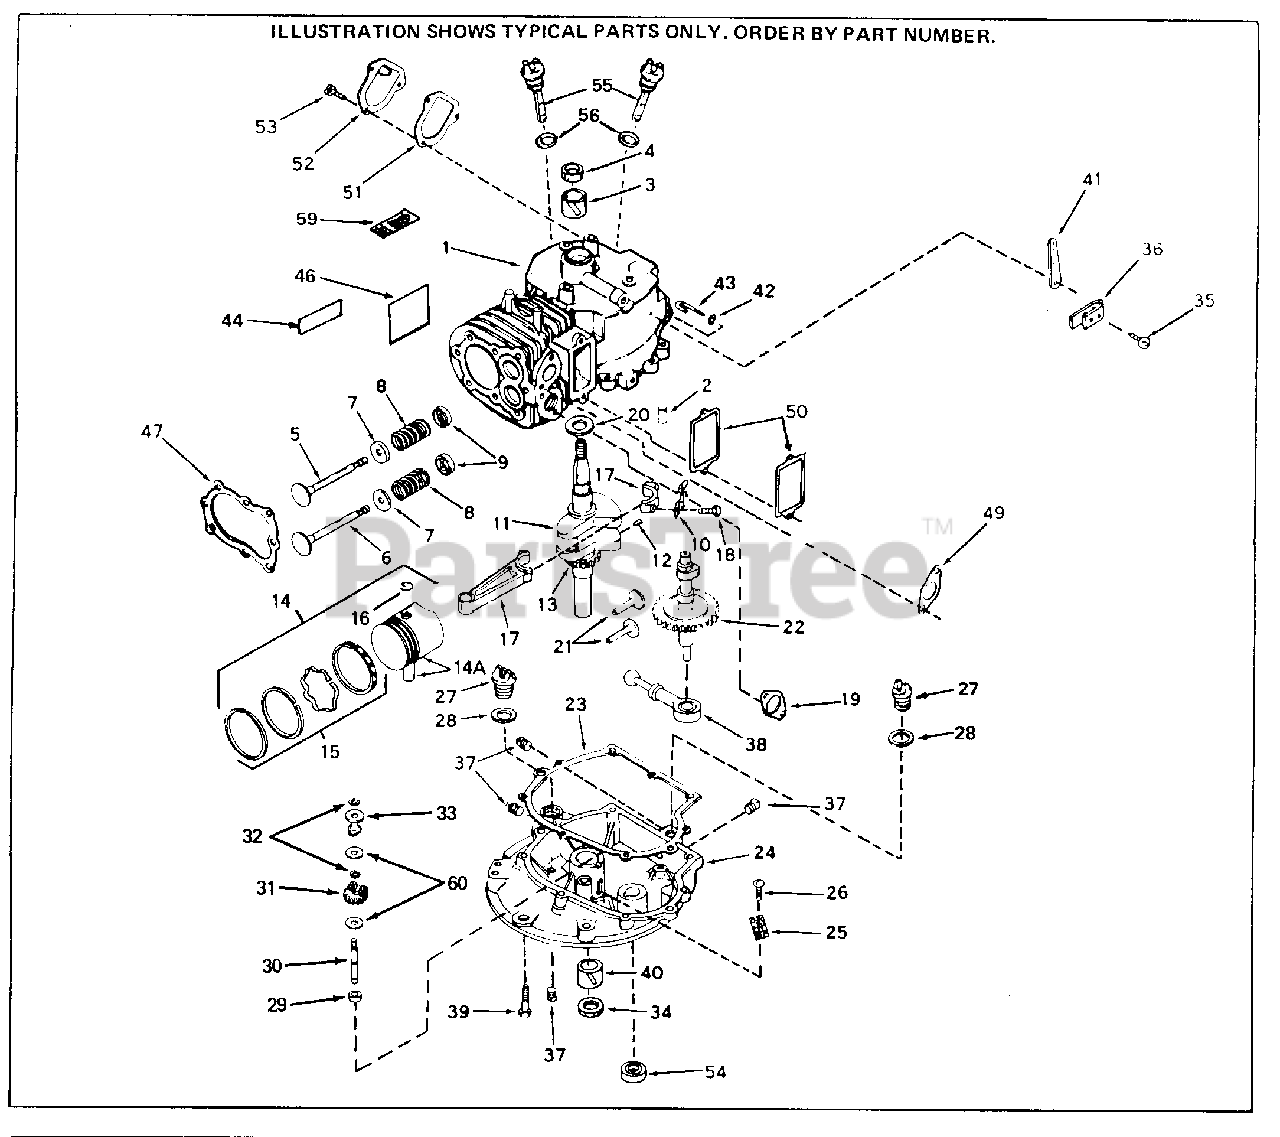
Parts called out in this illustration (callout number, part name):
1	"Cylinder (Incl. 2,4,44,51,52,53) 2-3/ 4" Bore
2	Dowel Pin
4	Seal, Oil
5	Intake Valve (Std) (Incl. 9)
5	Intake Valve (1/32" OS) (Incl. 9)
6	Exhaust Valve (Std.)(Incl. 151)
6	Exhaust Valve (1/32" OS) (Incl. 151)
7	Valve Spring Cap
8	Valve Spring
9	Cap, Lower valve spring
10	Plate, Lock Used only in early produc tion
11	Crankshaft (Incl. 12 & 13)
12	Pin, Crankshaft gear only)
13	Crankshaft Gear Early production only
14	Piston, Pin & Ring Set (Std) 2-3/4"Bo re
14	Piston, Pin & Ring Set (.010" OS)
14	Piston, Pin & Ring Set (.020" OS)
14A	Piston & Pin Ass'y. (Std)(Incl. 16) 2 -3/4"
14A	Piston & Pin Ass'y. (.010" OS) Incl. 16
14A	Piston & Pin Ass'y. (.020" OS) Incl. 16
15	Ring Set (Std) (2-3/4" Bore)
15	Ring Set (.010" OS)
15	Ring Set (.020 " OS)
16	Piston Pin Retaining Ring
17	Rod Assy., Connecting (Incl. 18)
18	Bolt, Connecting rod (Incl. 2 pcs.)
19	Gasket, Exhaust
21	Lifter, Valve
22	Camshaft (MCR)
23	Gasket, Mounting flange
24	Mounting Flange Ass'y. Incl. 27,28,30 ,34 & 37
25	Screen, Oil filter Early productionon ly
26	Screw, 8-32 x 5/16" Early productiono nly
27	Oil Fill Plug (Incl. 312) also availa ble in Packaged Part #740079
28	Oil Fill Plug Gasket
29	Spacer, Governor gear (Incl. 60)
30	Shaft, Mechanical governor
31	Gear Assy., Governor (Incl. 60)
32	Retaining Ring
33	Spool, Governor
34	Oil Seal
35	Screw, 8-32 x 5/16"
36	Clamp, Governor lever
37	Oil Drain Plug (Sq. hd., 1/4-18)req.)
37	Oil Drain Plug (Sq. hd., 1/4-18)equir ed)
38	Pump, Oil
39	Screw, 1/4-20 x 1-1/4"
40	Bushing, Crankshaft (Use as required)
41	Lever, Governor
42	Flat Washer
43	Rod, Governor (Incl. 42)
44	Decal, Model & Serial Number
46	Decal, Instruction
47	Gasket, Cylinder head
49	Intake Pipe Gasket
50	Valve Cover Gasket
51	Gasket, Oil fill tube
52	Cover, Oil fill tube
53	Screw, 10-24 x 7/16"
59	Decal, Name
60	Washer, Flat
